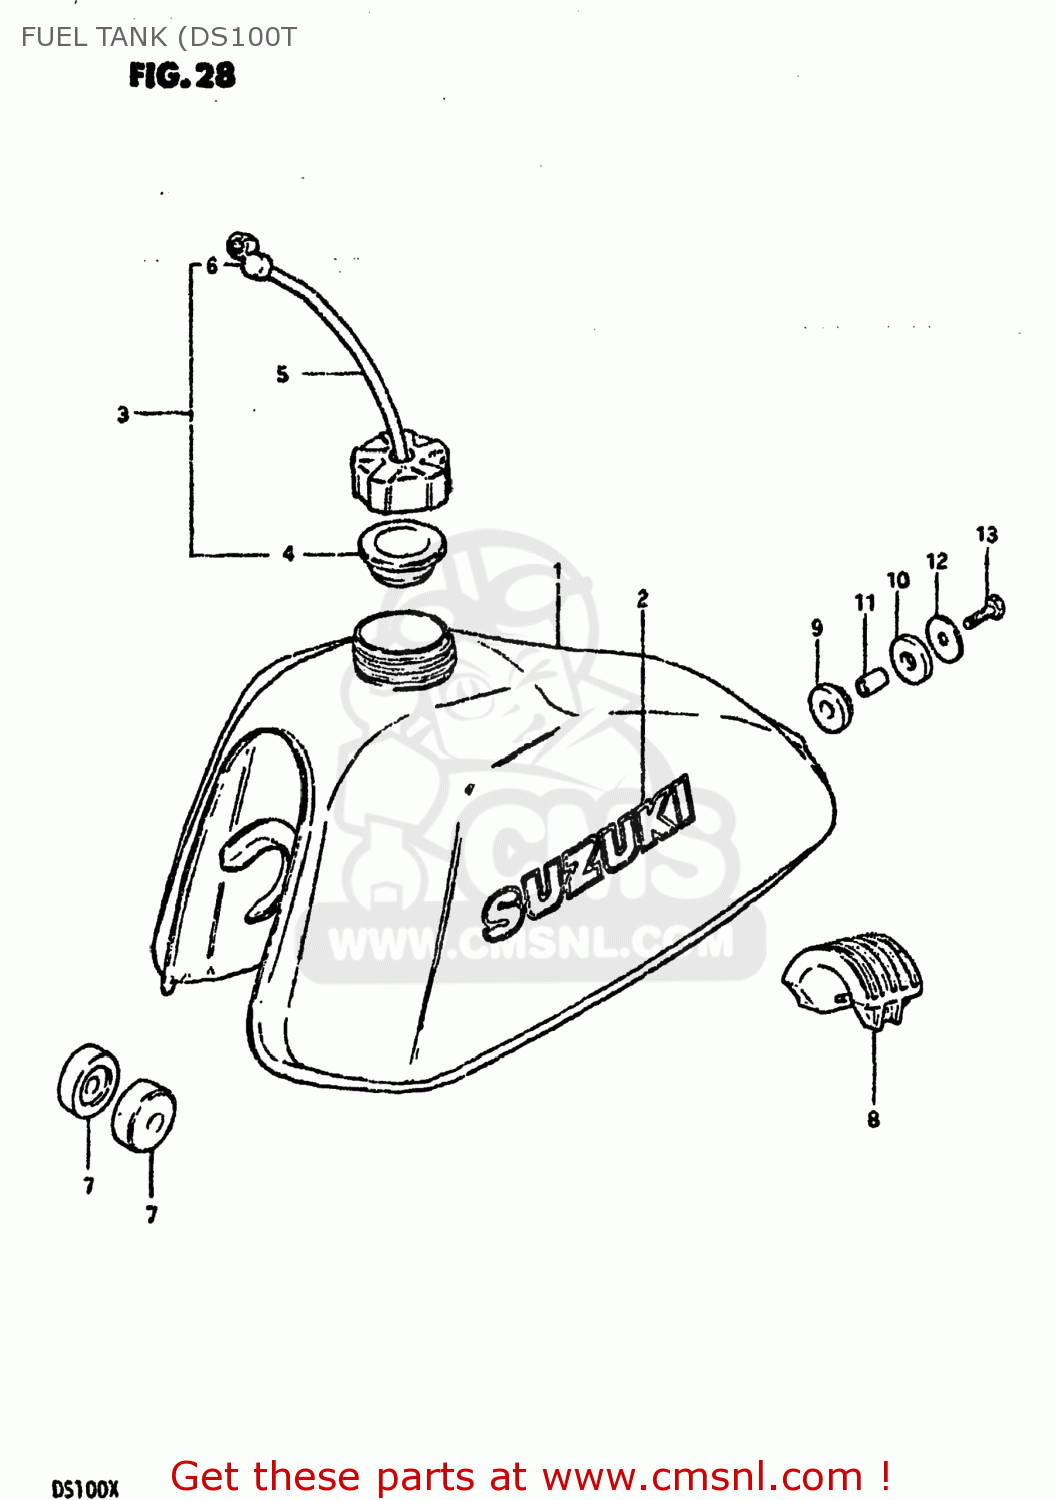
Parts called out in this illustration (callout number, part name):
1	TANK ASSEMBLY,FUEL
2	EMBLEM,FUEL TANK(WHITE)
3	CAP SET,FUEL TANK
4	GASKET,FUEL TANK CAP (NAS)
5	HOSE
6	CLAMP,FUEL TANK BREATHER HOSE
7	CUSHION
8	CUSHION,FUEL TANK
9	CUSHION
10	CUSHION
11	SPACER(8.5X12X19)
12	WASHER (8.5X29X1.6)
13	BOLT (8X30)
